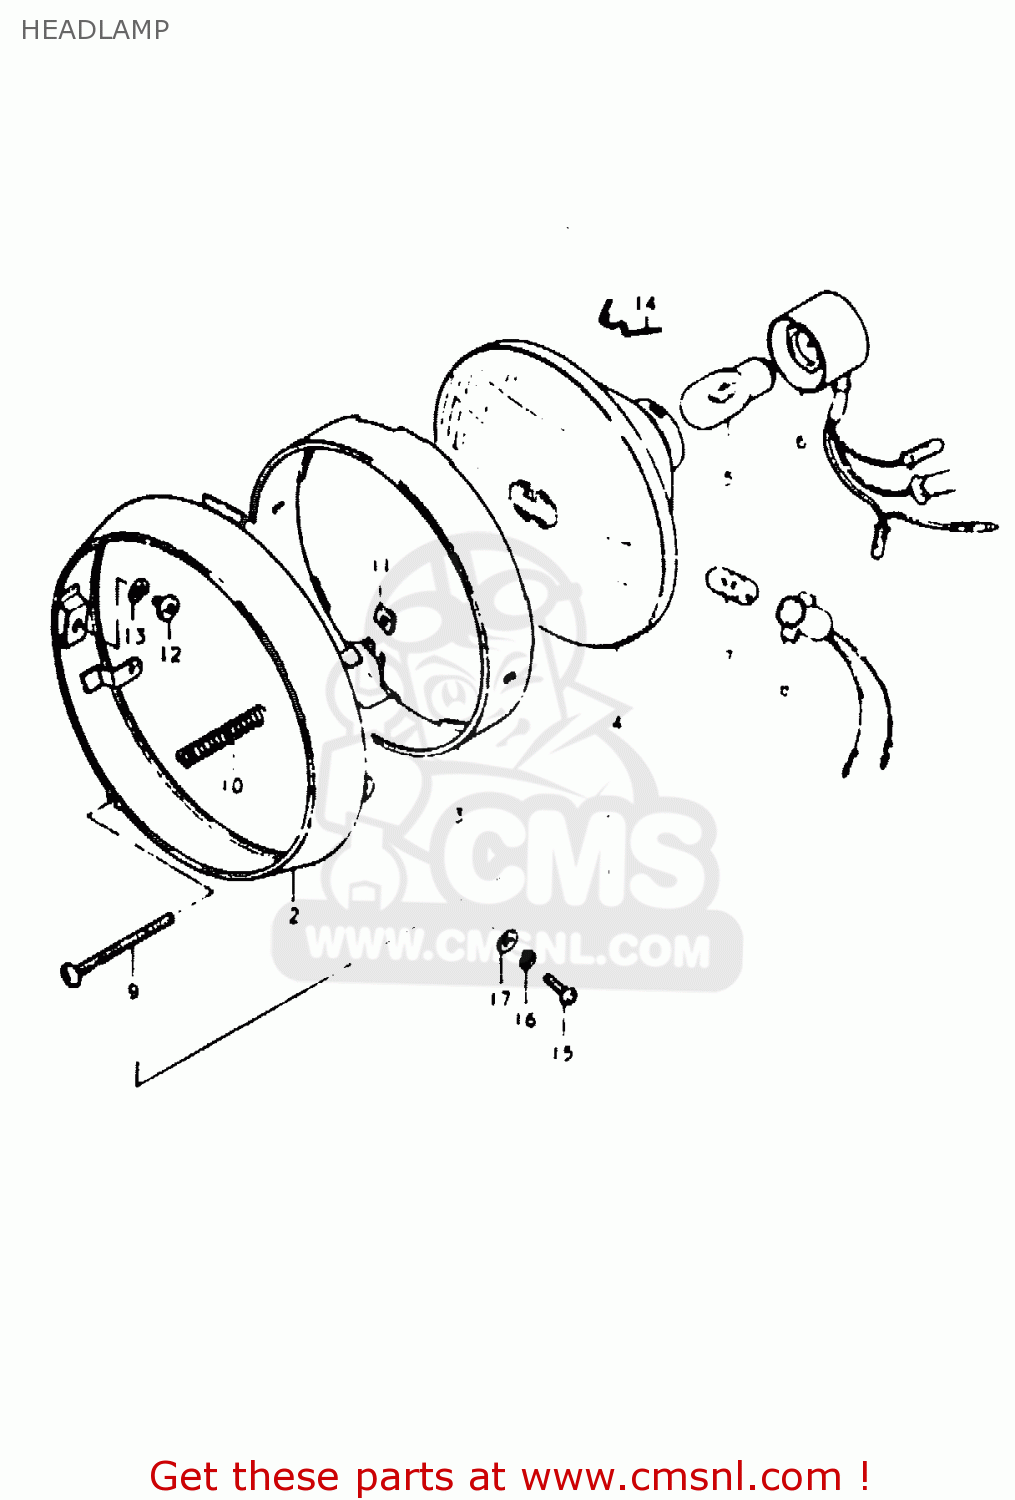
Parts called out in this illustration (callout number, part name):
1	HEADLAMP ASSY
2	RIM
3	RETAINER
4	UNIT
5	BULB (6V, 18/18W)
6	SOCKET
7	BULB(6V/3W)
8	SOCKET
9	SCREW,HEADLAMP ADJUST
10	SPRING,ADJUSTING
11	NUT
12	SCREW
13	LOCK WASHER
14	SPRING
15	SCREW
16	LOCK WASHER
17	WASHER
